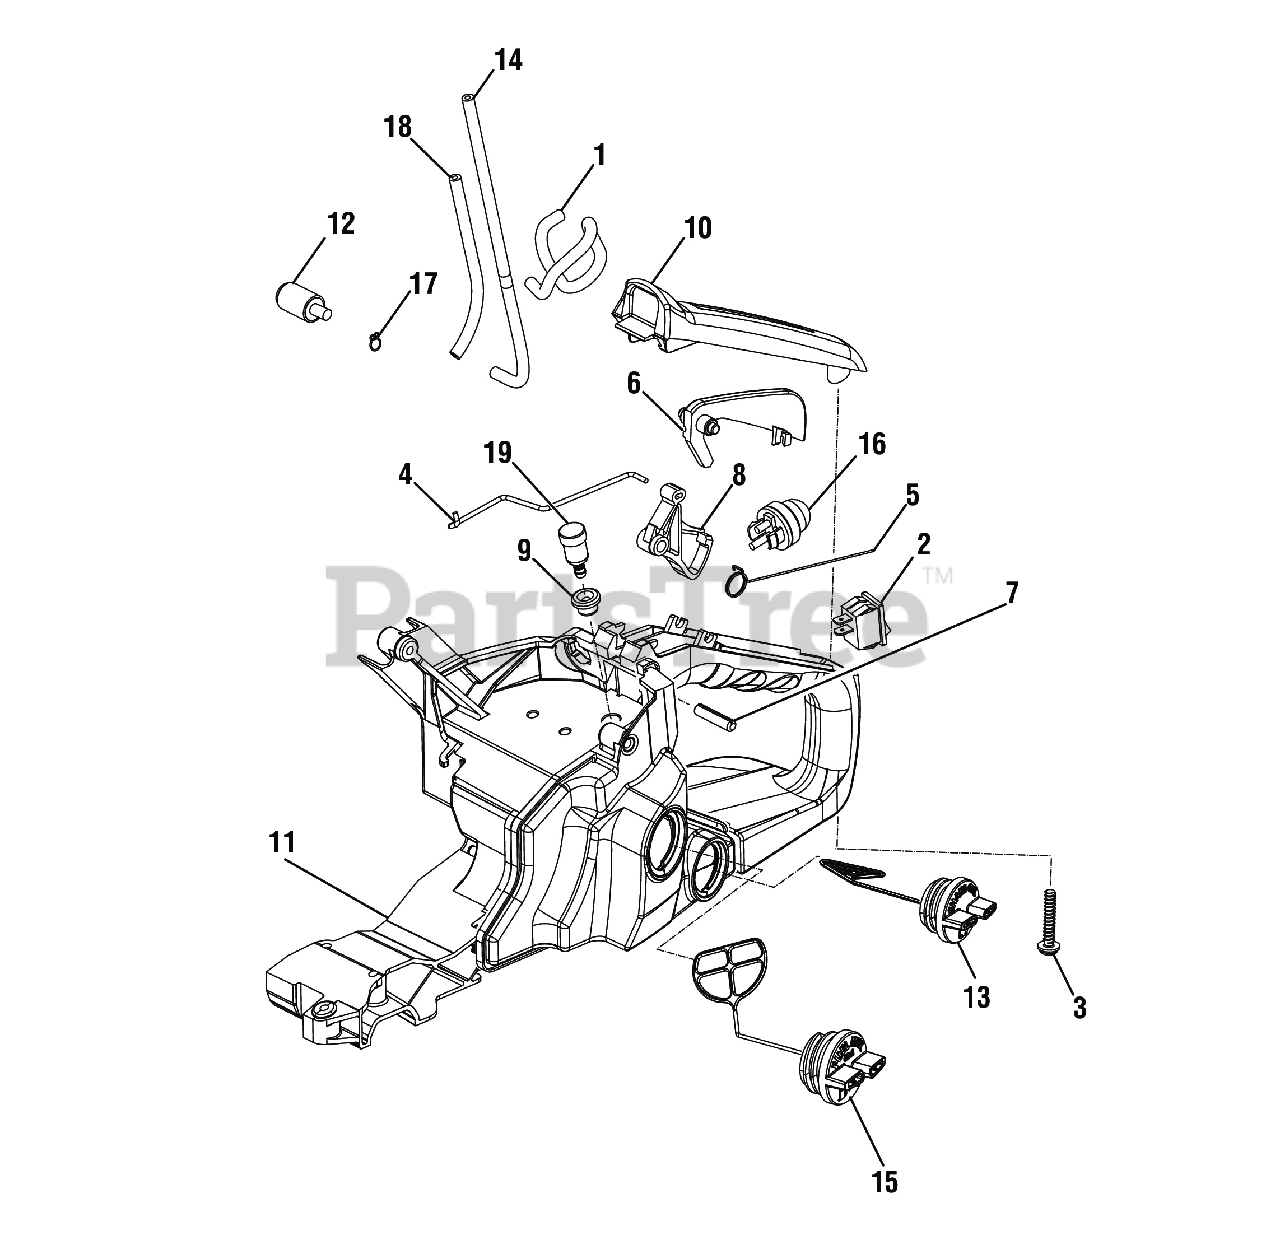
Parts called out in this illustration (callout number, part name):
1	Fuel Hose (Primer Assembly to Carburetor, 160 mm)
3	Screw (M5 x 27 mm, T25 Torx Pan Hd.)
4	Throttle Rod.
5	Throttle Spring
6	Hose (Oil Pump Outlet)
7	Spring Pin
8	Throttle Trigger
10	Grip Cover
11	Rear Handle Assembly
12	Fuel Filter Assembly
13	Oil Cap Assembly
14	LP-1500 Tubing (205.00 mm)
15	Fuel Cap Assembly
16	Primer Bulb Assembly
17	CLIP-HOSE (ID 4.9)
18	Fuel Hose (Primer Assembly to Tank, 153 mm)
19	Fuel Breather Assembly
